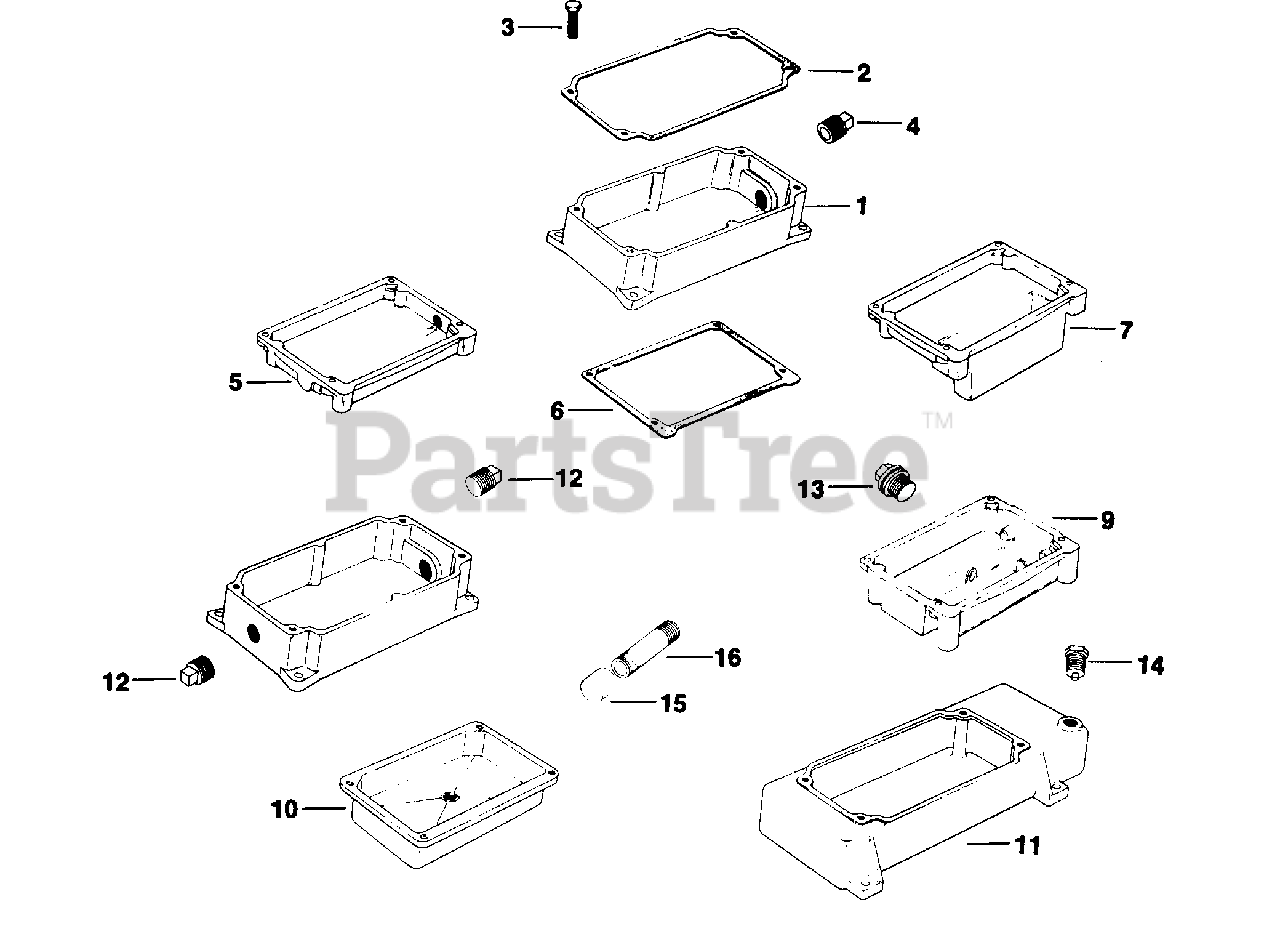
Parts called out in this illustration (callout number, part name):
1	BASE
2	GASKET, OIL PAN
4	PLUG,PIPE SQ HD 3/4" USE 25 139 56-S
